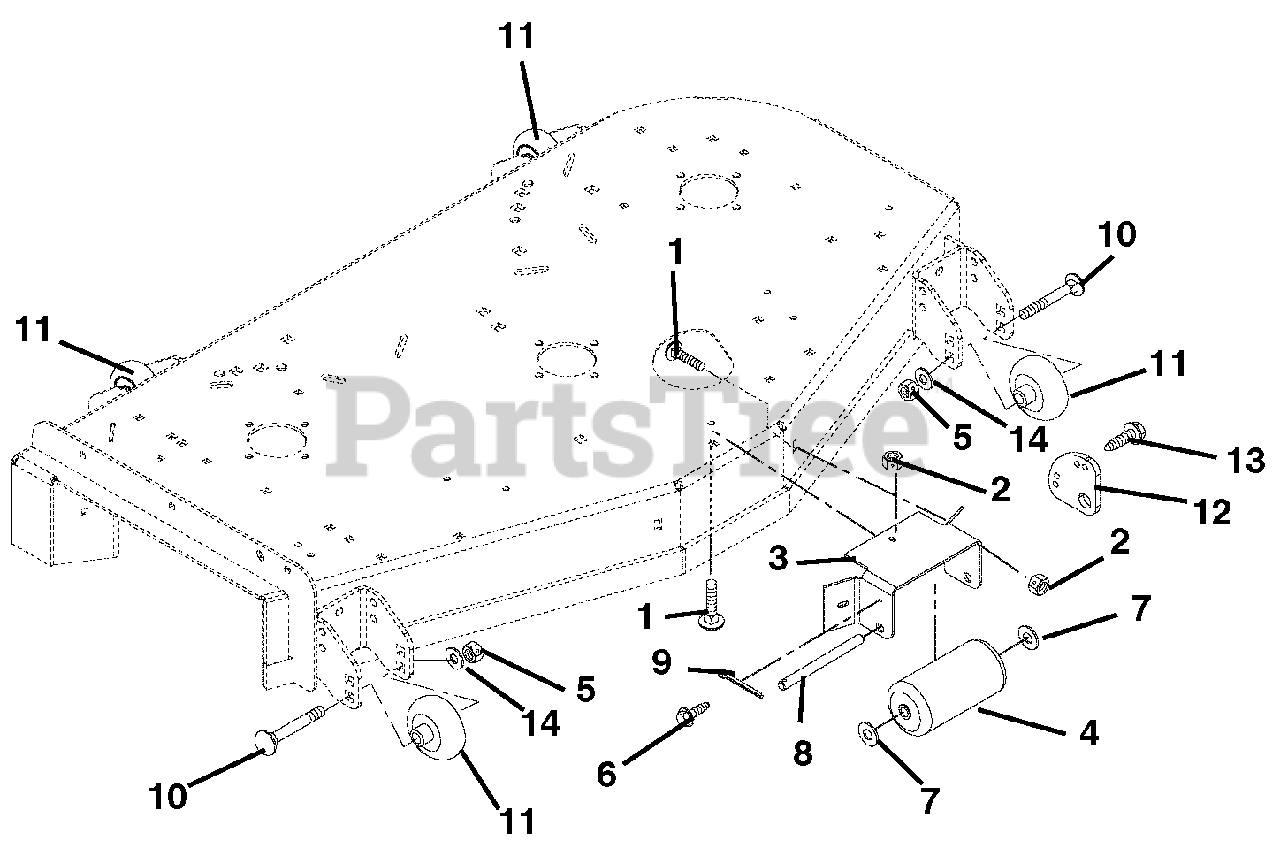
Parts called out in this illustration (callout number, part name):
1	Bolt-Round Head Square Neck .38-16 x 1.00 Grade 5
2	Nut-Locking-Top-Flange .38-16
3	Bracket- Anti-Scalp Roller
5	Nut-Locking-Nylon .50-13
6	Screw-Tapping .25-20 x .75 Hex Washer Head
7	Washer-Flat-Steel .656 x 1.31 x .095
9	Pin-Cotter .25 x 2.00
10	Bolt-Round Head Square Neck .50-13 x 5.00 Grade 2
11	Wheel, 3 x 5
12	Anti-Scalp Washer
13	Screw-Tapping .25-20 x .62 Hex Washer Head
14	Washer-Flat-Steel .531 x 1.06 x .095
